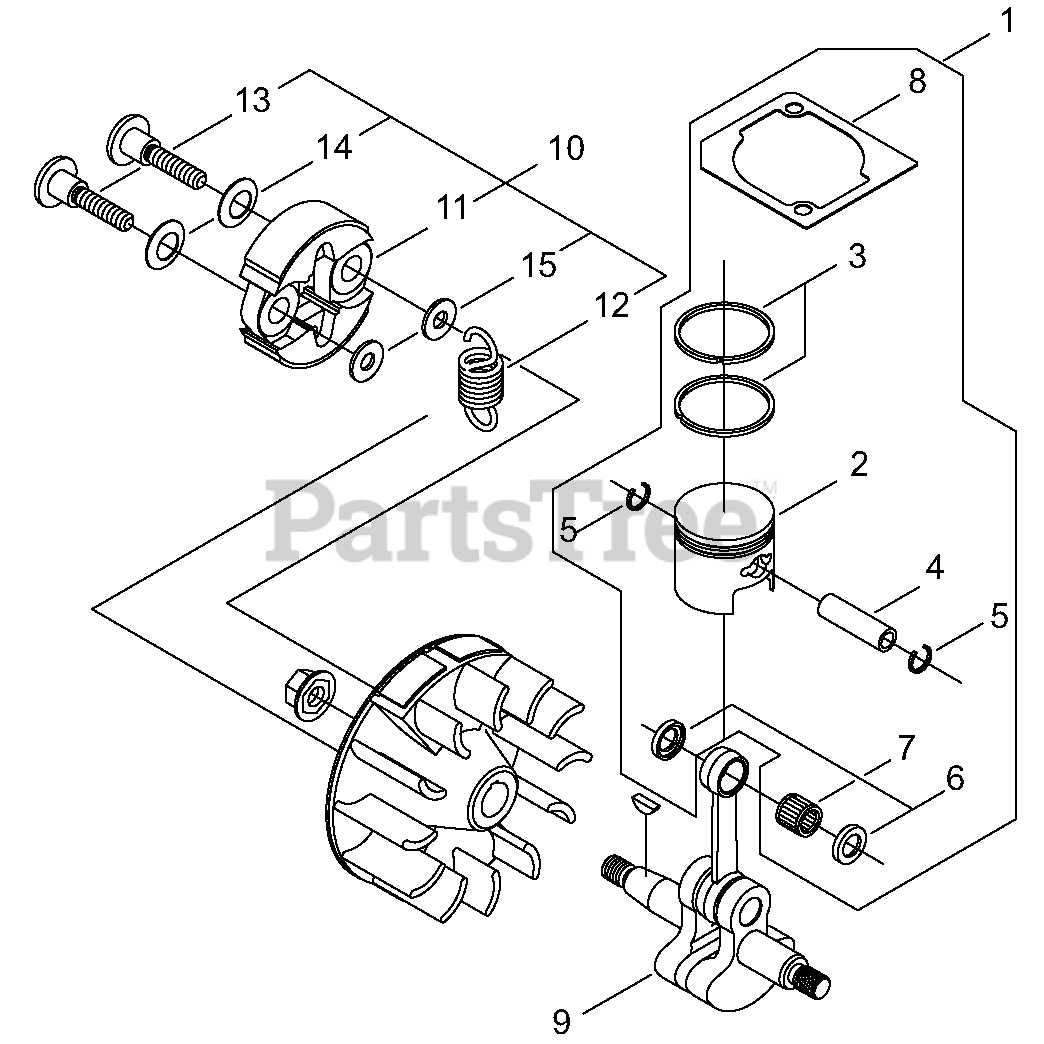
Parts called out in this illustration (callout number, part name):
1	PISTON ASSY
2	PISTON
3	RING, PISTON
4	PIN, PISTON
5	RING, RETAINING
6	SPACER, PISTON
7	BEARING, NEEDLE - 8
8	GASKET, CYLINDER
9	CRANKSHAFT ASSY
10	CLUTCH ASSY
11	CLUTCH SHOE SET
12	SPRING, CLUTCH
13	BOLT, CLUTCH
14	WASHER - SPRING
15	WASHER - 6
